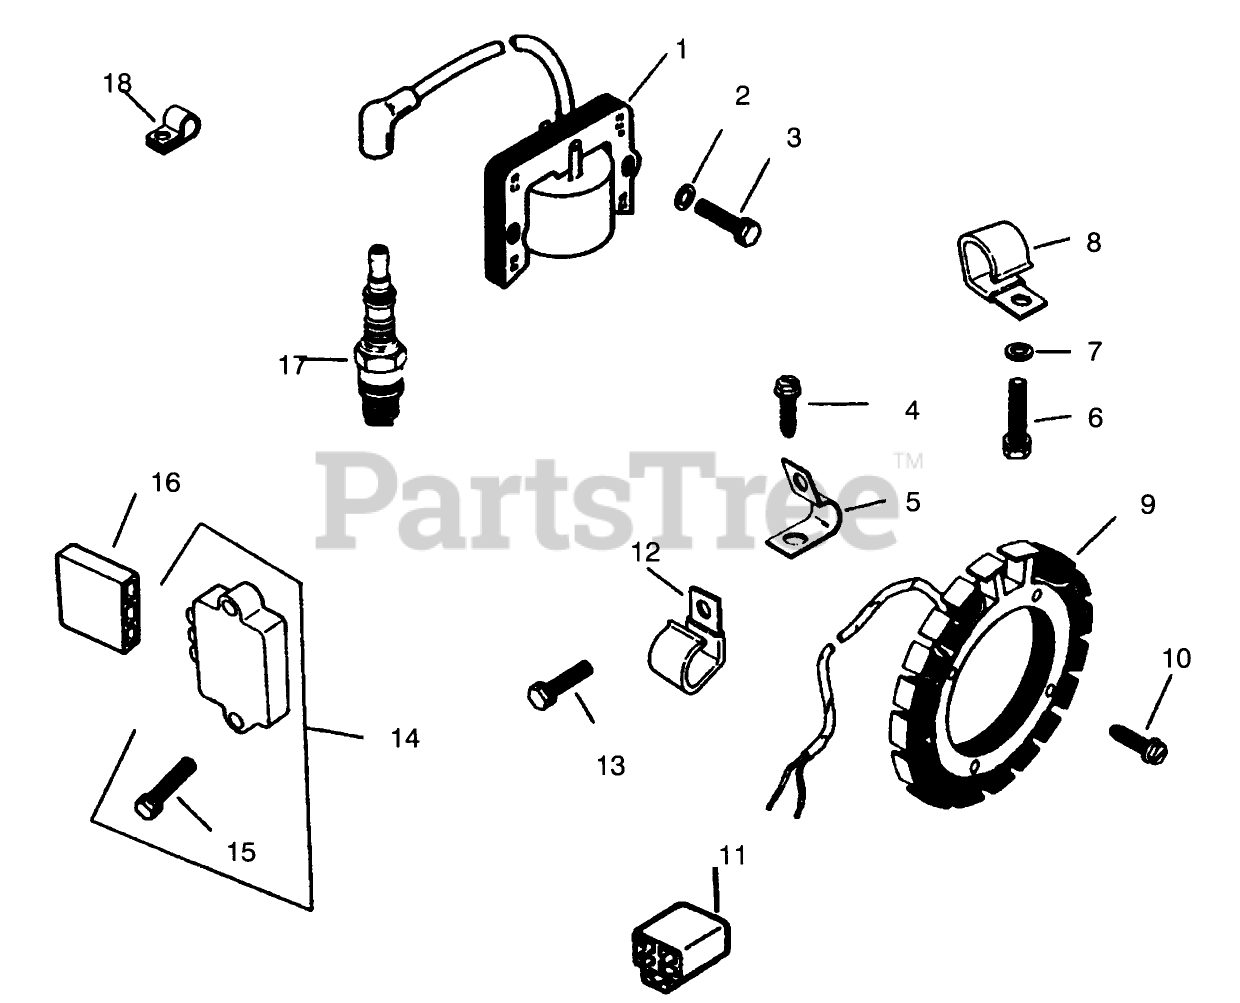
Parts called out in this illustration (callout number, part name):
1	KOHLER 47-584-02
2	KOHLER X-25-72
3	KOHLER X-156-1
4	KOHLER X-67-59
5	KOHLER X-728-1
6	KOHLER X-67-83
7	KOHLER X-25-72
8	VNDR #255173
9	KOHLER 237878
10	KOHLER X-67-51
11	KOHLER 48-155-01
12	CLIP
13	SCREW-HH
14	KOHLER 25-755-03
15	VNDR #X-132-5
16	KOHLER 236602
17	VNDR #235041-5
18	KOHLER 210281
